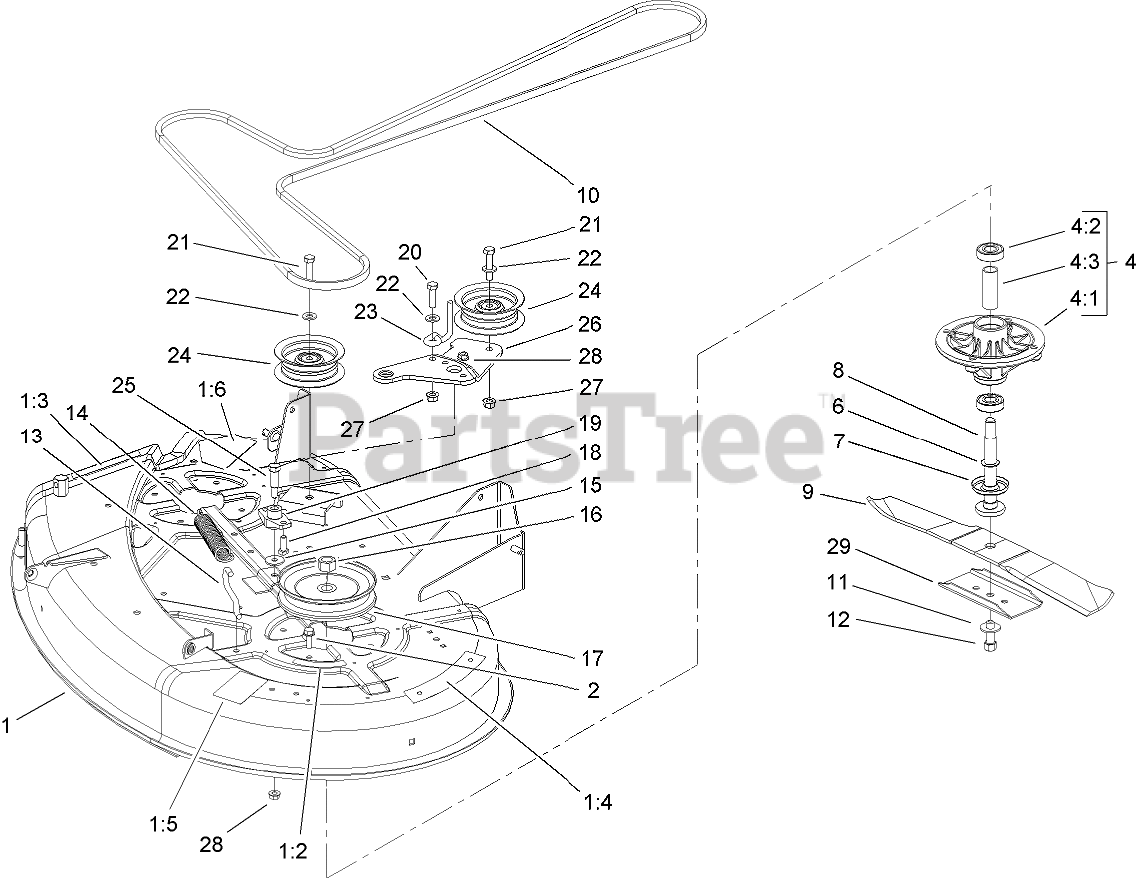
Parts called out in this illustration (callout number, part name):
1	42IN DECK ASM
1:2	DECAL-DANGER, SHIELD
1:3	DECAL-DANGER, DEFLECTOR
1:4	DECAL-DANGER
1:5	DECAL-ROUTING, BELT
1:6	DECAL-DANGER
2	SCREW-TAPTITE
4	Spindle ASM
4:1	HOUSING-SPINDLE
4:2	BEARING-BALL
4:3	SPACER
6	SPACER
7	SHIELD-BEARING
8	SHAFT-SPINDLE
10	BELT-V
11	WASHER-BELLEVILLE
12	SCREW-HH
13	HOOK-RETURN, SPRING
14	SPRING-EXTENSION
15	WASHER-PIVOT
16	NUT-HEX
17	PULLEY
18	SCREW-HH
19	BUSHING-ARM, IDLER
20	SCREW-HH
21	SCREW-HH
22	WASHER-FLAT
23	GUIDE-IDLER, BELT
24	PULLEY-IDLER, FLAT
25	SCREW-SHOULDER, HH
26	ARM-IDLER
27	NUT-HF
28	NUT-HF
29	STIFFENER-BLADE
